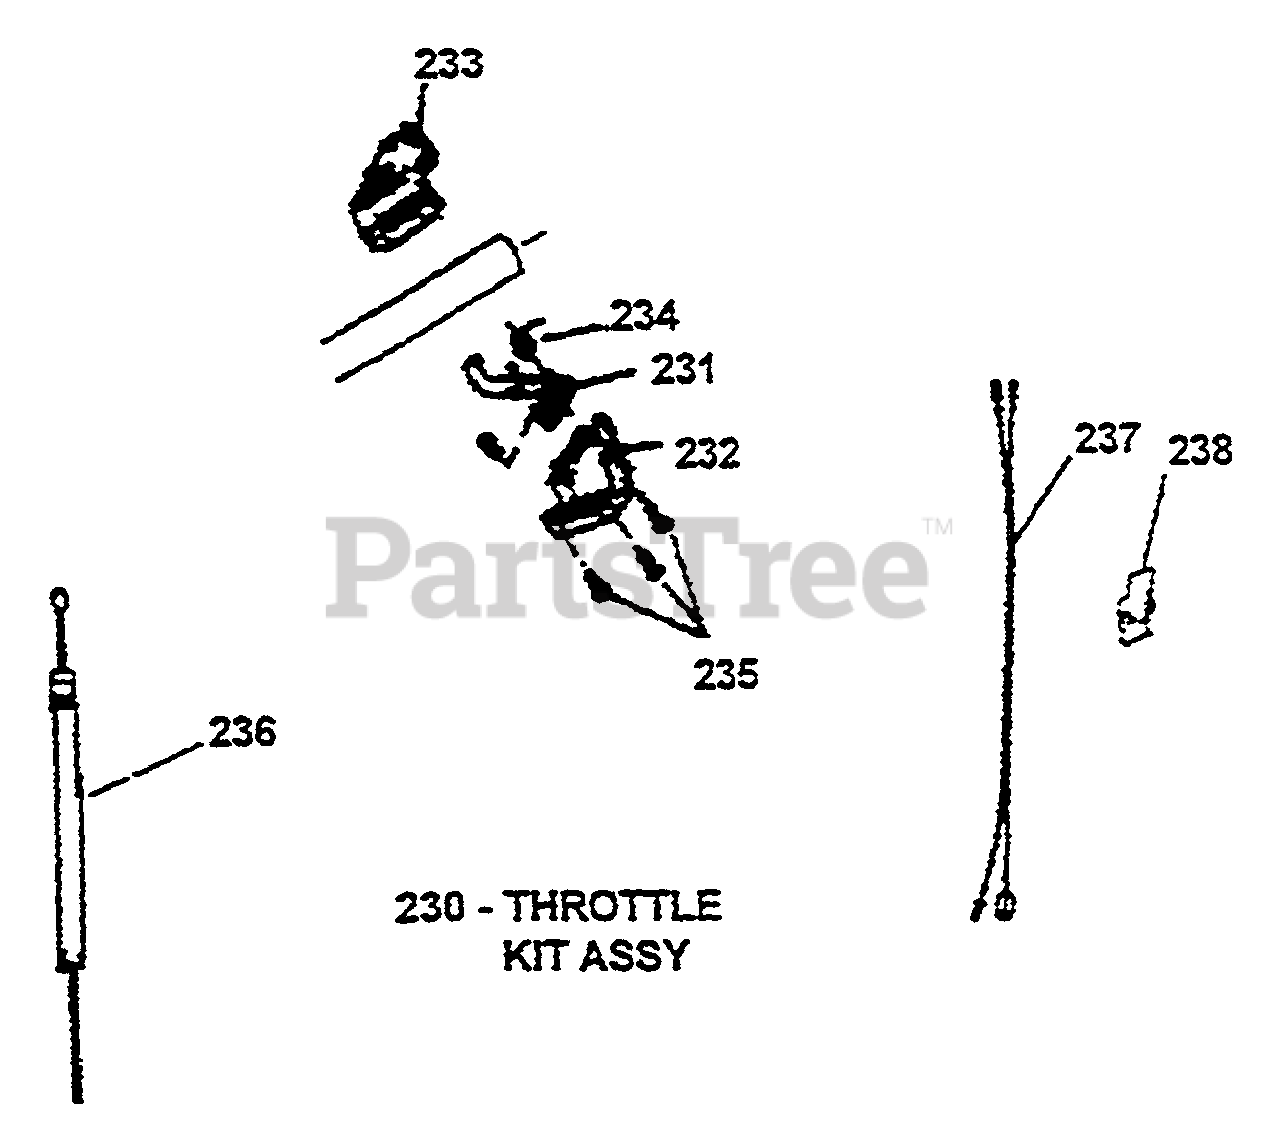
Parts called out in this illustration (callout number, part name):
230	THROTTLE KIT ASSY
231	THROTTLE LEVER
232	CLAMP L.H.
233	CLAMP R.H.
234	SPRING, THROTTLE TRIGGER
235	SCREW
236	THROTTLE CABLE
237	HARNESS
238	SWITCH
